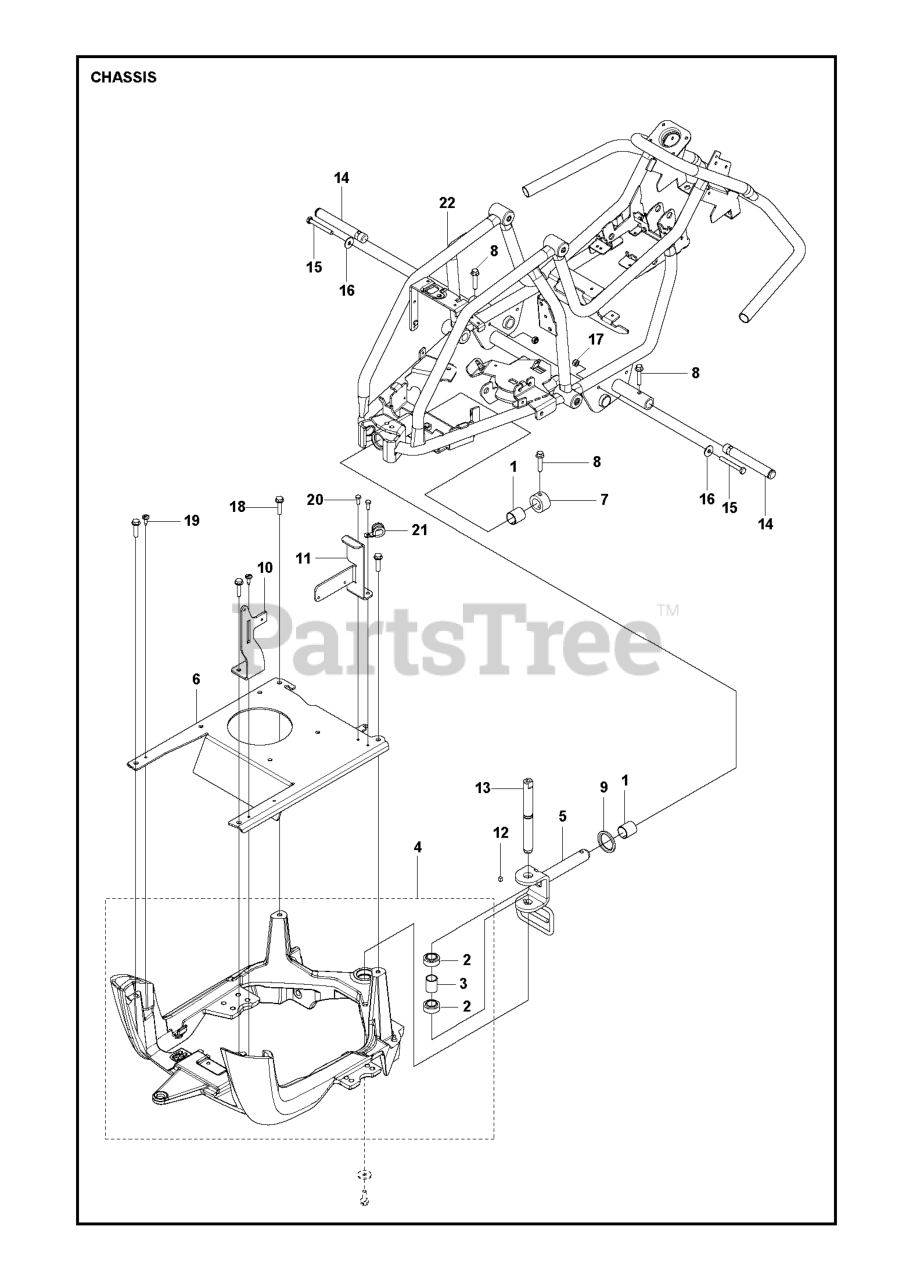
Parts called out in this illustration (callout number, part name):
1	BUSHING
5	SWING AXLE
7	STOP SLEEVE
8	BOLT FLANGE - M8X40\
14	WHEEL AXLE
17	LOCKNUT M8
18	SCREW EHHFM
20	SCREW
21	HOSE CLAMP
22	FRAME FRONT ASSY
